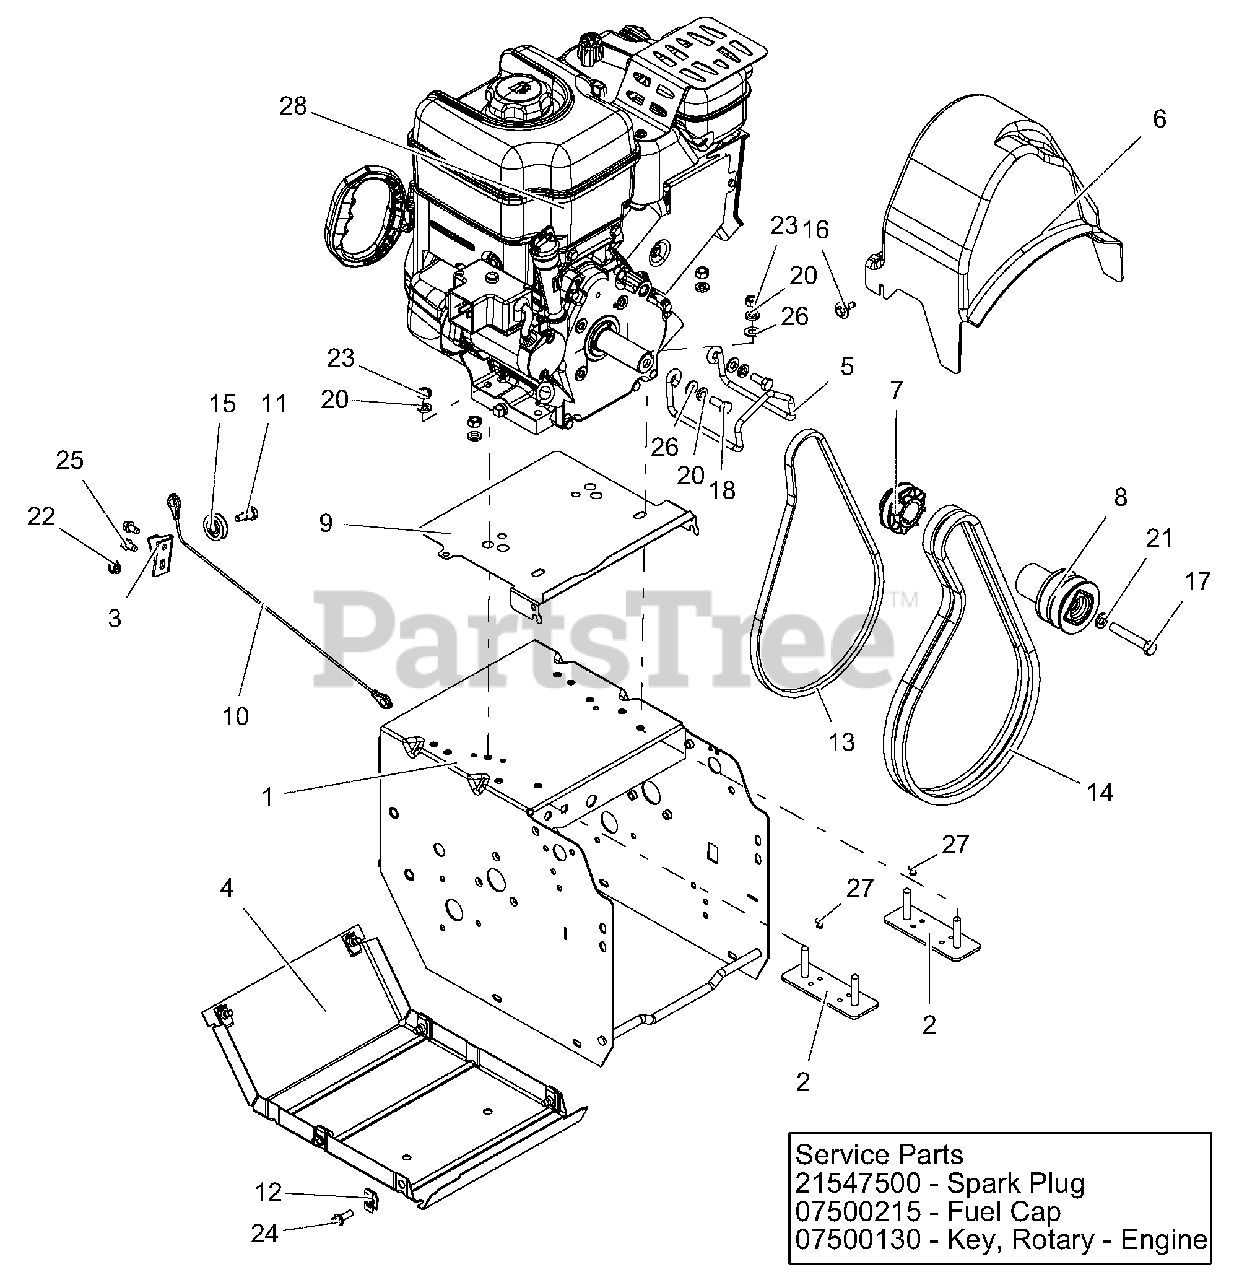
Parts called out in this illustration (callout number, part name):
1	WELDMENT, FRAME - DELUXE 16"
2	STRAP,ENGINE BOLT,ARIENS SML
3	BRACKET, CABLE PULLEY
4	COVER, BOTTOM
5	FINGER, BELT
6	BELT COVER
7	SHEAVE, DRIVE
8	SHEAVE,ATTACHMENT 2-GRV
9	BAFFLE,ENGINE,ARIENS SML BLOCK
10	CABLE, LOWER TRACTION (DELUXE)
11	BOLT, SHLDR-.375X.375X.25-20
12	NUT-RTNR .25-20X.56
13	V-BELT, 3L-WRAPPED
14	V-BELT, HA-RAW EDGE (SET)
15	PULLEY, CABLE
16	SCR-TAP .25-20X.5 CAPTIVE
17	BLT-HEX .38-24X2.25 YWZC GR5
18	BLT-HEX .31-24X.75 YWZC GR5
20	WSHR-LK .312X.097 HVY YWZC
21	@WSHR-LK .38X.094 REG YWZC
22	@NUT-LK-CTR-FLG .25-20 YWZC
23	@NUT-HEX .31-18 YWZC
24	BLT-HEX .25-20X.75 HWH YZ GR5
25	SCR-TAP .25-20X.50 HWH TR YWZ
26	@WSHR-FL-STL.344X.688X.065YWZC
27	RVT-POP .187 YZ
28	ENGINE, BRIGGS PF 1150, 120V
